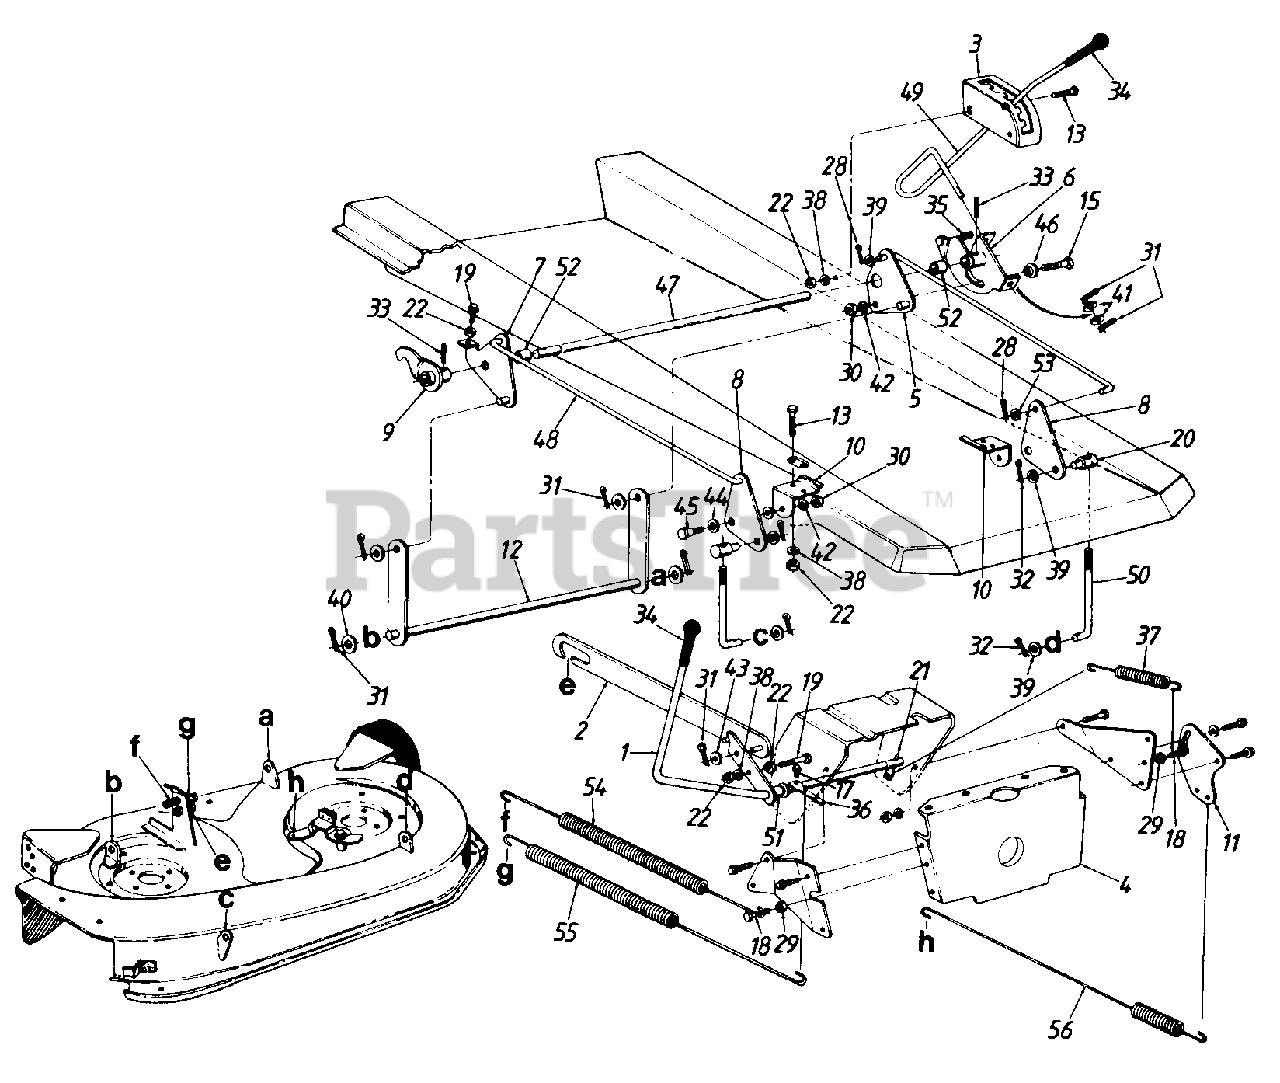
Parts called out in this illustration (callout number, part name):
1	Blade Engagement Lever Ass'y.
2	Deck Drive Control Brkt. Ass'y.
5	Deck Lift Brkt. Ass'y.
6	Deck Lift Handle Retainer Ass'y.
7	Deck Lift Brkt. Ass'y.
8	Deck Lift Bracket
9	Deck Lift Float Brkt Ass'y.
10	Deck Lift Pivot Brkt.
11	Blade Brake Spring Brkt.
12	Stabilizer Shaft Ass'y.
13	Hex Bolt 5/16-18 x .75" Lg.
15	Hex Bolt 3/8-16 x 1" Lg.
17	Hex Wash. Hd. Scr. 1/4-20 x 1.5" Lg.
18	Hex Bolt 5/16-18 x 1-1/2" (Gr. 5)
19	Hex Wash.-Tap Scr. 5/16-18 x 1.25" Lg.
20	Ferrule
21	Clevis Pin
22	Hex Nut 5/16-18 Thd.
28	Cotter Pin 3/32" Dia.
29	Hex Nut 1/4-20 Thd.
30	Hex Nut 3/8-16 Thd.
31	Cot-Pin 1/8" Dia. x 1" Lg.
32	Int. Cot. Pins 3/8" Dia.
33	Spring Pin Spir. 1/4" Dia.
35	Compression Spring 1.04" Lg.
36	Switch Actuator
37	Ext. Spring 5.86" Lg.
38	L-Wash 5/16" I.D.
39	Fl-Wash. .385 I.D. x .62
40	Fl-Wash. .635 I.D. x 1.12
41	Fl-Wash. .531 I.D. x .930
42	L-Wash. 3/8" I.D.
43	Fl-Wash. .385 I.D. x .87 O.D.
44	Spring Washer .530 I.D.
45	Shld. Bolt .500" Dia. x .215"Lg.
46	Shld Spacer.625" I.D.
47	Rear Hot Adj. Shaft
50	J-Bolt 5.4" Lg.
51	Spacer .511 I.D.
52	Spacer .885 I.D.
53	Fl-Wash. 5/16" I.D.
54	Ext. Spring 22.05" Lg.
55	Ext. Spring 13.84" Lg.
56	Ext. Spring 15.38" Lg.
